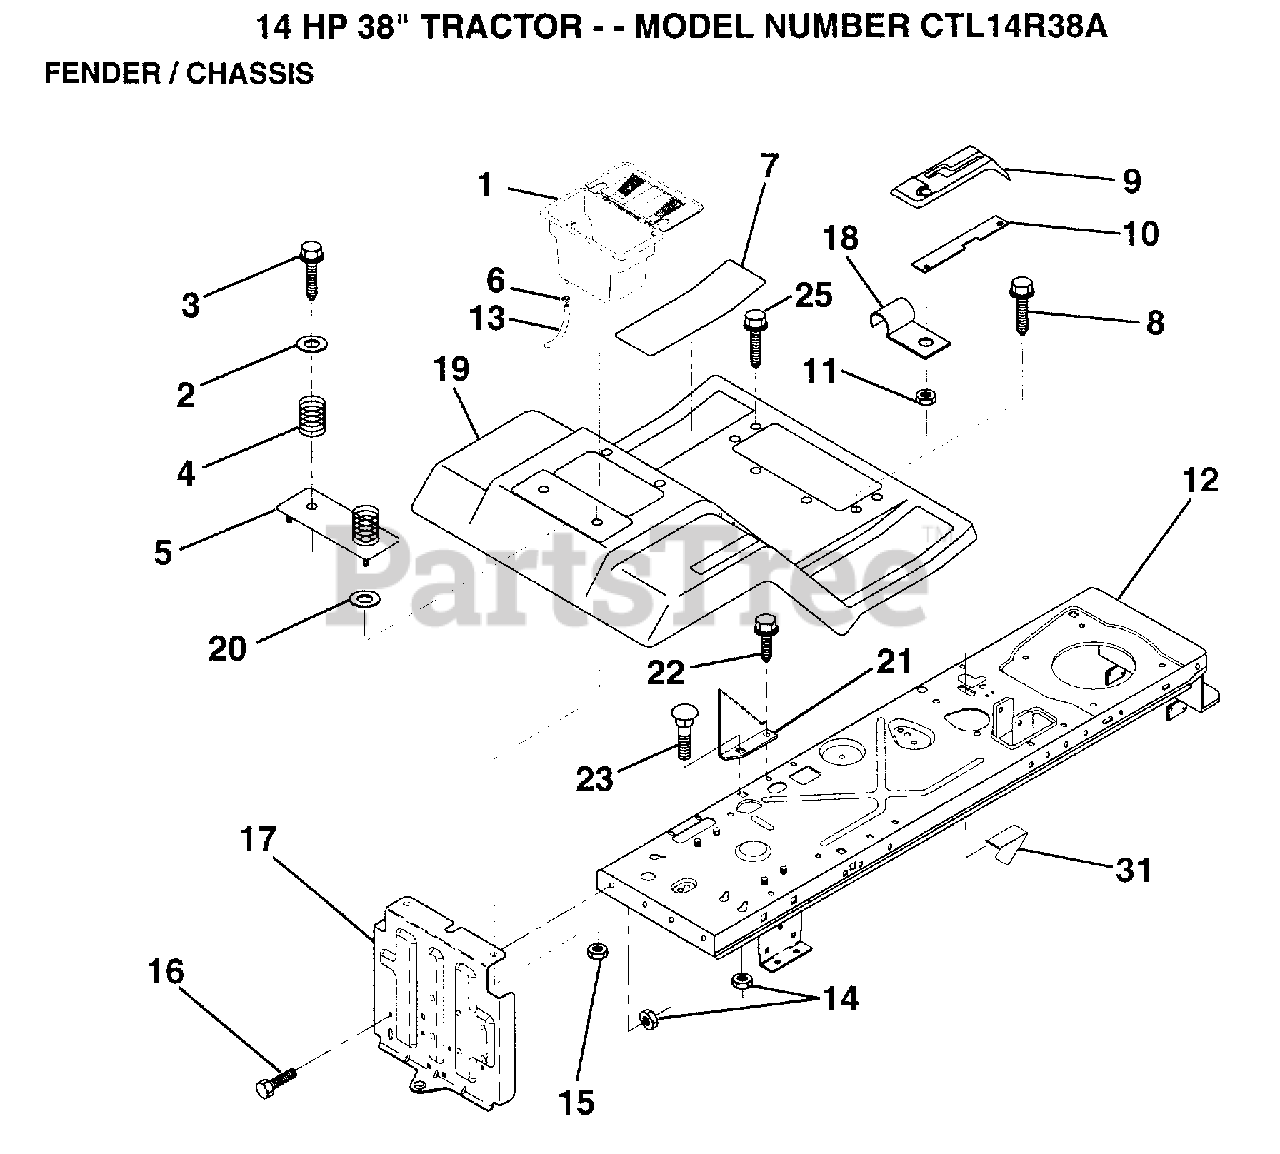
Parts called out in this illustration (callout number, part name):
2	WASHER
3	SCREW
4	SPRING COMPRESSIO
5	BTRY FENDER PLATE
6	HOSE CLAMP T
7	PAD FOOTREST
8	SCREW
10	PLATE LOCK SHIFT
11	NUT
13	TUBE T
14	NUT
15	NUT
16	BOLT
17	DRAWBAR ASM LR
18	"CLIP,INSULATOR"
19	FENDER/FOOT MS505
21	BRACKET STOP DEPT
22	SCREW LT
25	SCREW TI
